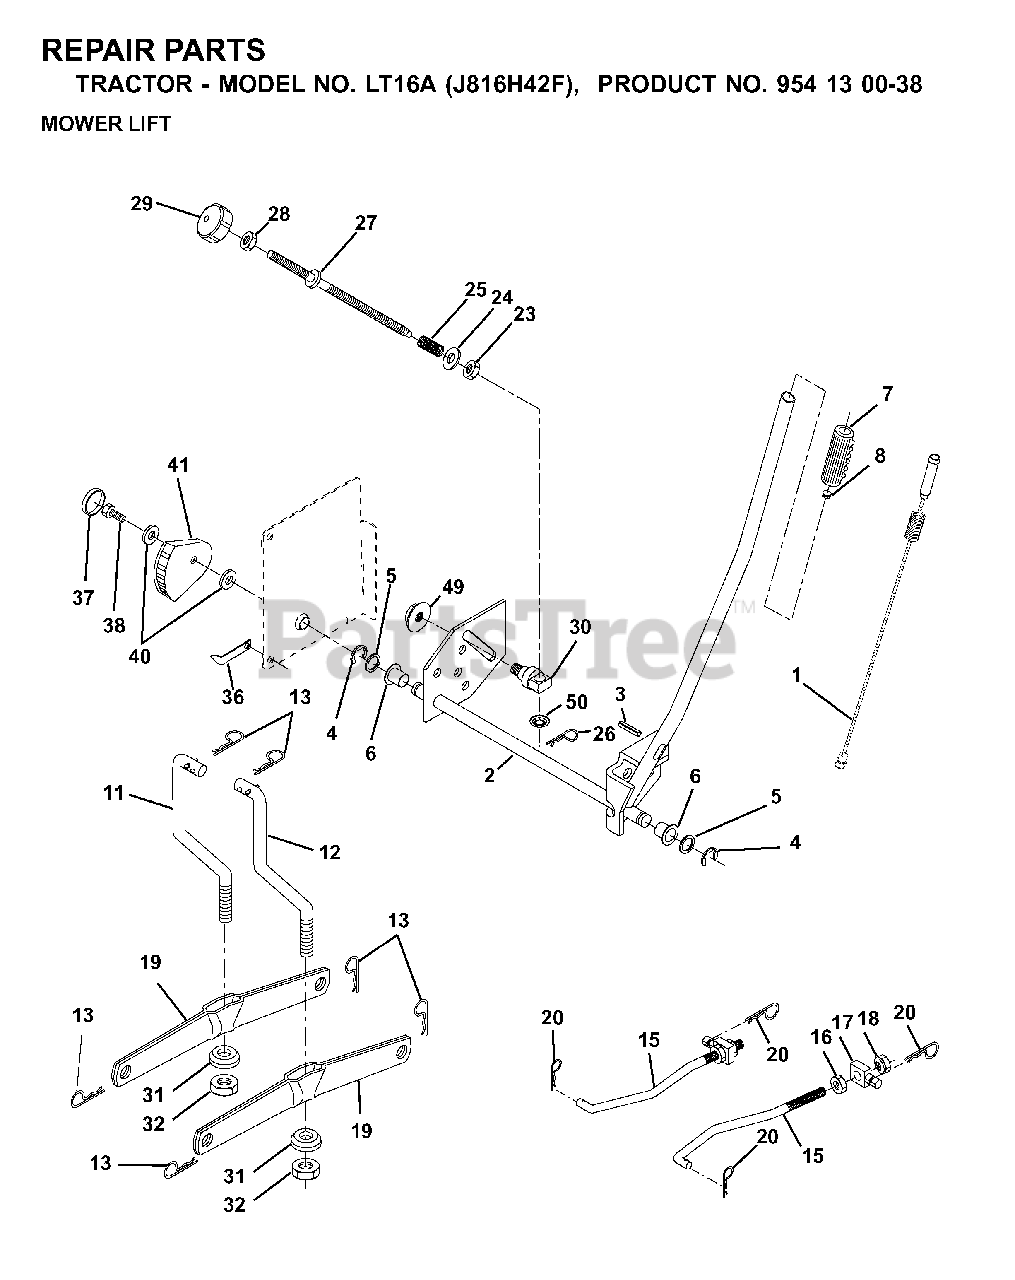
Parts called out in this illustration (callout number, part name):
1	WIRE ASM INNER W/ PLUNGER LT
2	SHAFT ASM R HANDLE
3	PIN GROOVE
4	RETAINING RING LT
6	BEARING.NYLON
7	GRIP HANDLE
11	LINK LIFT LH
12	LINK LIFT RH
13	RETAINER-SPRNG RB
15	LINK FRONT
16	NUT
17	TRUNION
18	NUT
19	ARM.REAR.SUSPENSION
20	SPRING RETAINER
25	SPRING**
26	RETAINER CLIP
27	ROD ADJ LIFT
28	NUT
29	KNOB INF 3/8-16
31	BEARING PIVOT
32	NUT CROWNLOCK 3/8-24
36	POINTER, HEIGHT INDICATOR
37	PLUG,HOLE
38	SCREW 5/16-18X1
41	IND. HEIGHT STLT
49	NUT
50	NUT PUSH M
